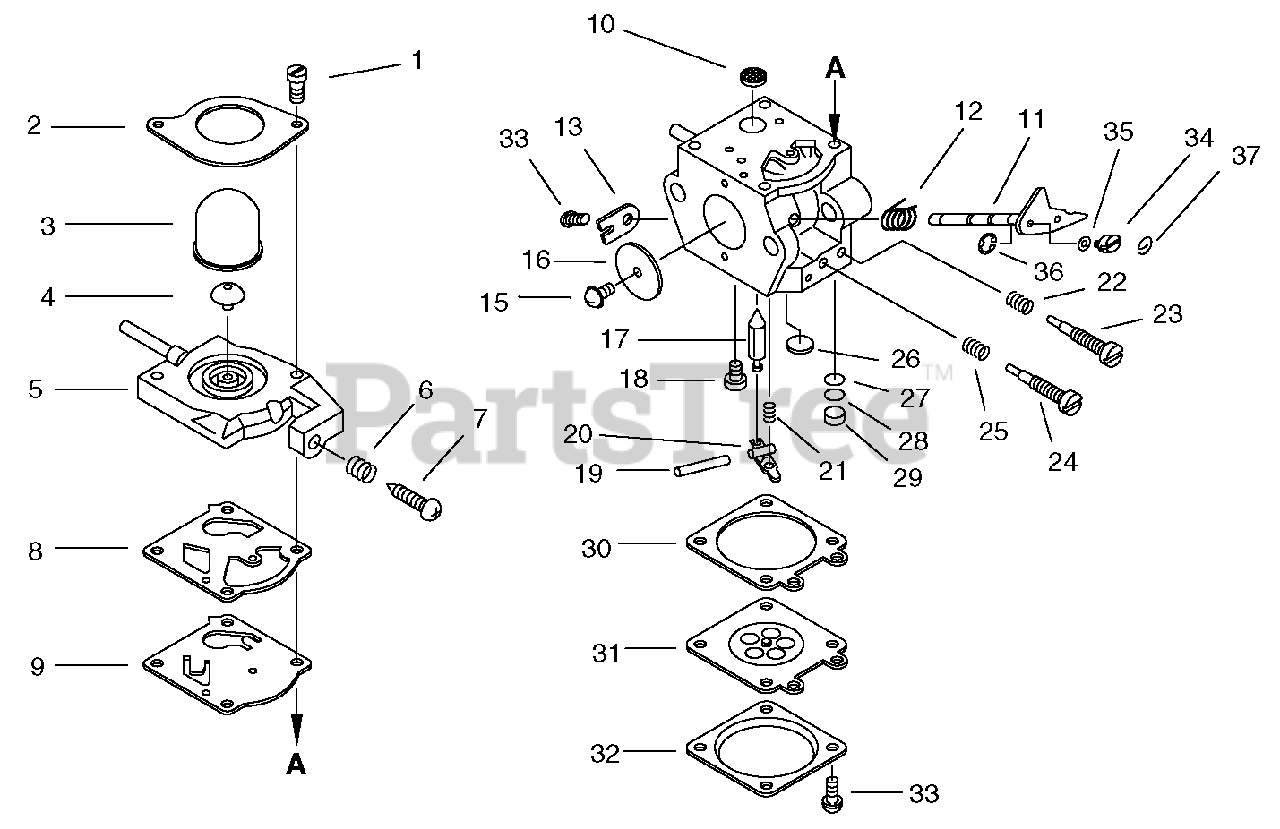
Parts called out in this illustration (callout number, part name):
2	RETAINER, PURGE BULB
3	BULB, PURGE
4	VALVE, CHECK
5	COVER, FUEL PUMP
6	SPRING, IDLE ADJUST
7	SCREW, IDLE ADJUST
8	GASKET, FUEL PUMP
9	DIAPHRAGM, FUEL PUMP
10	SCREEN, FUEL INLET
11	SHAFT, THROTTLE
12	SPRING, THROTTLE
13	CLIP, THROTTLE SHAFT
16	VALVE, THROTTLE
17	VALVE, INLET NEEDLE
18	SCREW, METERING LEVER PIN
19	PIN, METERING LEVER
20	LEVER, METERING
21	SPRING, METERING LEVER
22	SPRING, HIGH NEEDLE
23	NEEDLE, HIGH SPEED
24	NEEDLE, LOW SPEED
25	SPRING, NEEDLE
26	PLUG, WELCH
27	SCREEN, CHECK VALVE
28	RING, RETAINING
29	PLUG, CUP
30	GASKET, METERING DIAPHRAGM
31	DIAPHRAGM, METERING
32	COVER, METERING DIAPHRAGM
